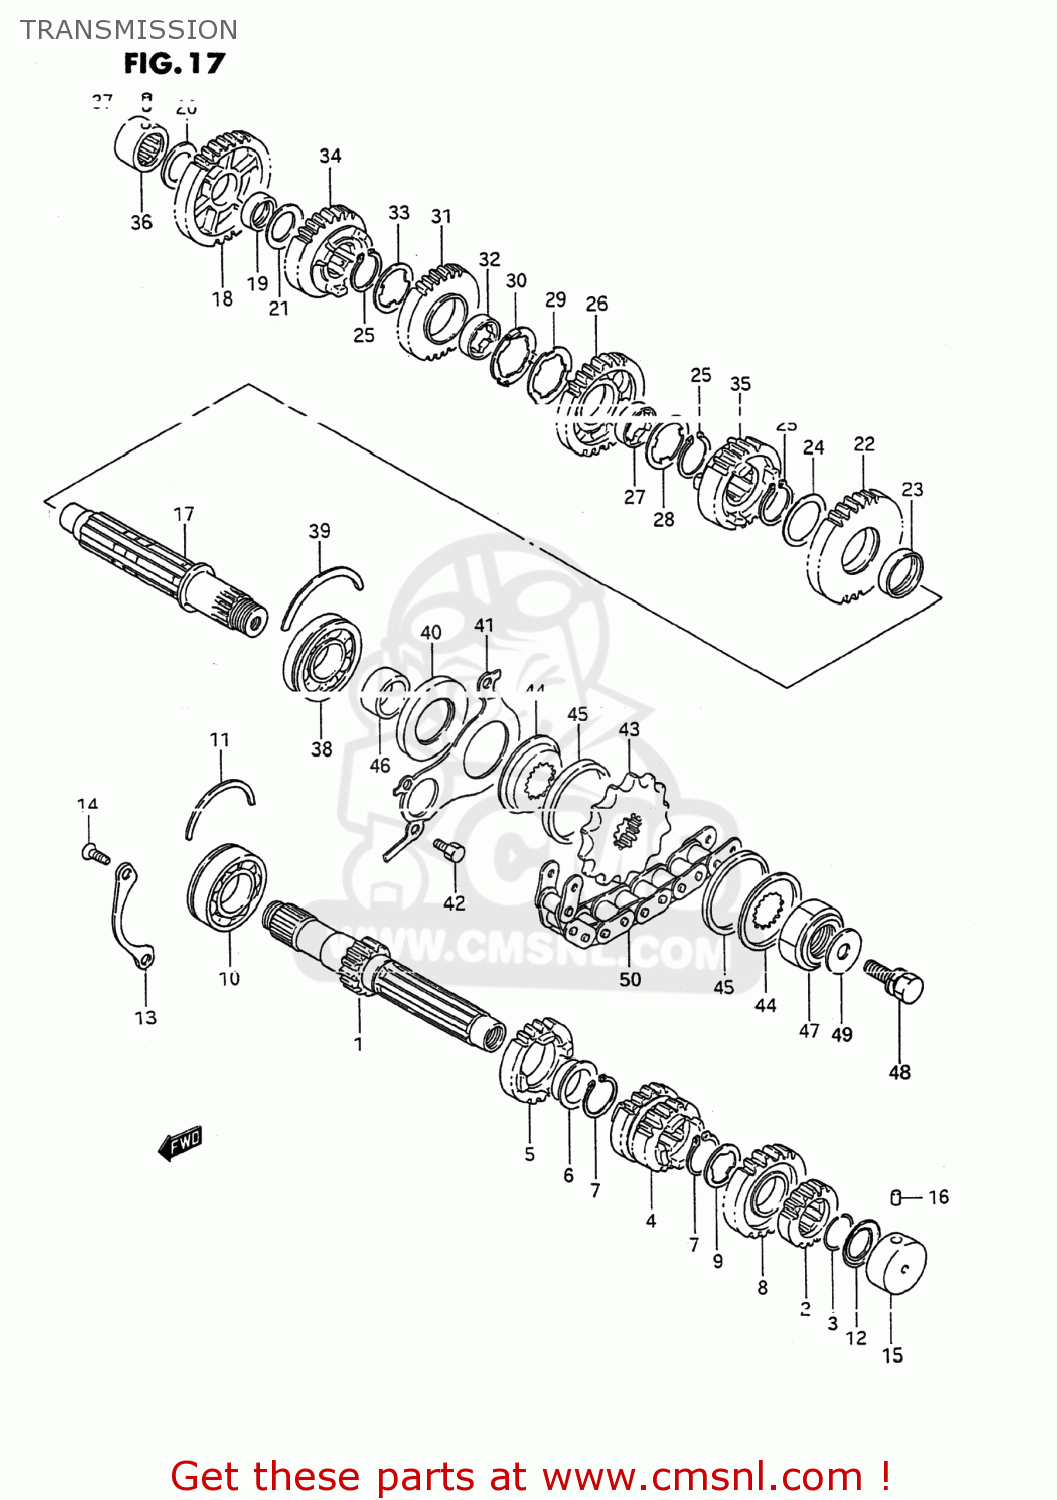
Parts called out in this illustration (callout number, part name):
1	SHAFT,COUNTER(NT:12)
2	GEAR,2ND DRIVE(NT:16)
3	CIRCLIP
4	GEAR,3RD & 4TH DRIVE(NT:17/20)
5	GEAR,5TH DRIVE(NT:22)
6	BUSHING
7	RING,SNAP
8	GEAR,SIXTH DRIVE
9	WASHER,LOCK
10	BEARING(25X62X17)
11	C-RING
12	SEAL,OIL(20X31.2X2.7)
13	RETAINER,CNTR SHAFT BEARING
14	SCREW
15	BEARING(20X34X17.5)
16	PIN
17	SHAFT,DRIVE
18	GEAR,FIRST DRIVEN
19	BUSH(22X26X9)
20	WASHER
21	WASHER
22	GEAR,2ND DRIVEN(NT:33)
23	BUSH(28X32X8)
24	WASHER, THRUST
25	CIRCLIP
26	GEAR,3RD DRIVEN(NT:28)
27	BUSH
28	WASHER,LOCK
29	WASHER,LOCK
30	WASHER
31	GEAR,FOURTH DRIVEN
32	BUSH
33	WASHER,LOCK
34	GEAR,5TH DRIVEN(NT:27)
35	GEAR,6TH DRIVEN
36	BEARING(20X34X20)
37	PIN
38	BEARING(25X62X17)
39	C-RING
40	SEAL,OIL(34X62X6)
41	RETAINER,DRIVE SHAFT OIL SEAL
42	BOLT
43	SPROCKET,ENGINE
44	HOLDER,SPROCKET DAMPER
45	DAMPER,SPROCKET
46	SPACER(25X34X16.1)
47	NUT
48	BOLT
49	WASHER
50	CHAIN,DRIVE(112LE)
